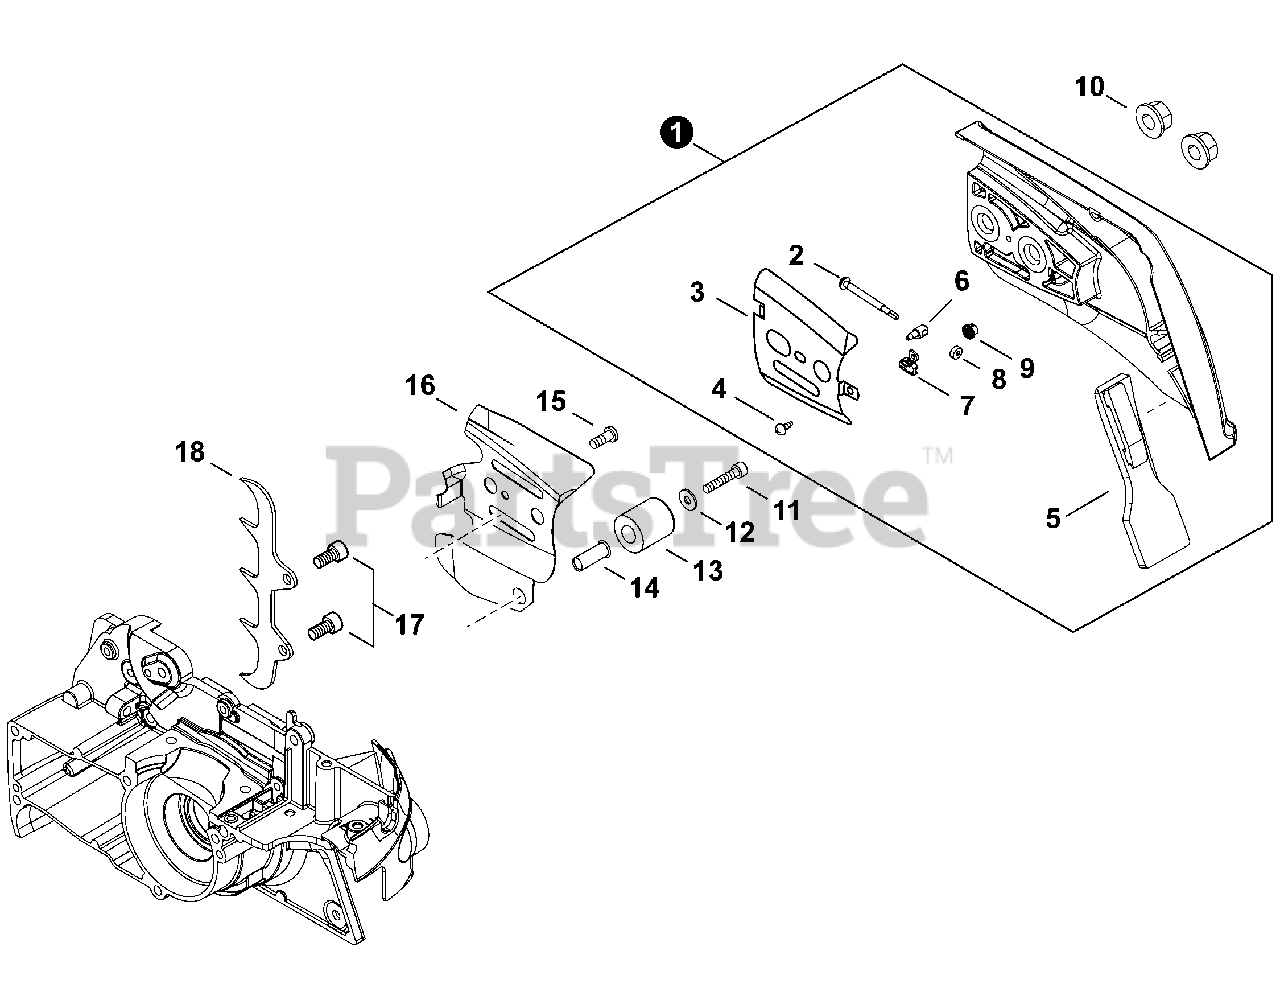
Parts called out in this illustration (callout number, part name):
1	COVER ASSY, CLUTCH
2	SCREW, CHAIN TENSION
3	PLATE, GUIDE - OUTER
4	SCREW 4×8
5	PROTECTOR
6	TENSIONER, CHAIN
7	COLLAR 8
8	GEAR, BEVEL
9	GEAR, BEVEL
10	NUT, FLANGE M8×1.25
11	BOLT 5×30
12	WASHER, FLAT 5.5×10×0.8
13	CHAIN CATCHER
14	COLLAR 5
15	SCREW M4×7
16	PLATE, GUIDE - INNER
17	BOLT 5×12
18	SPIKE, BUMPER
